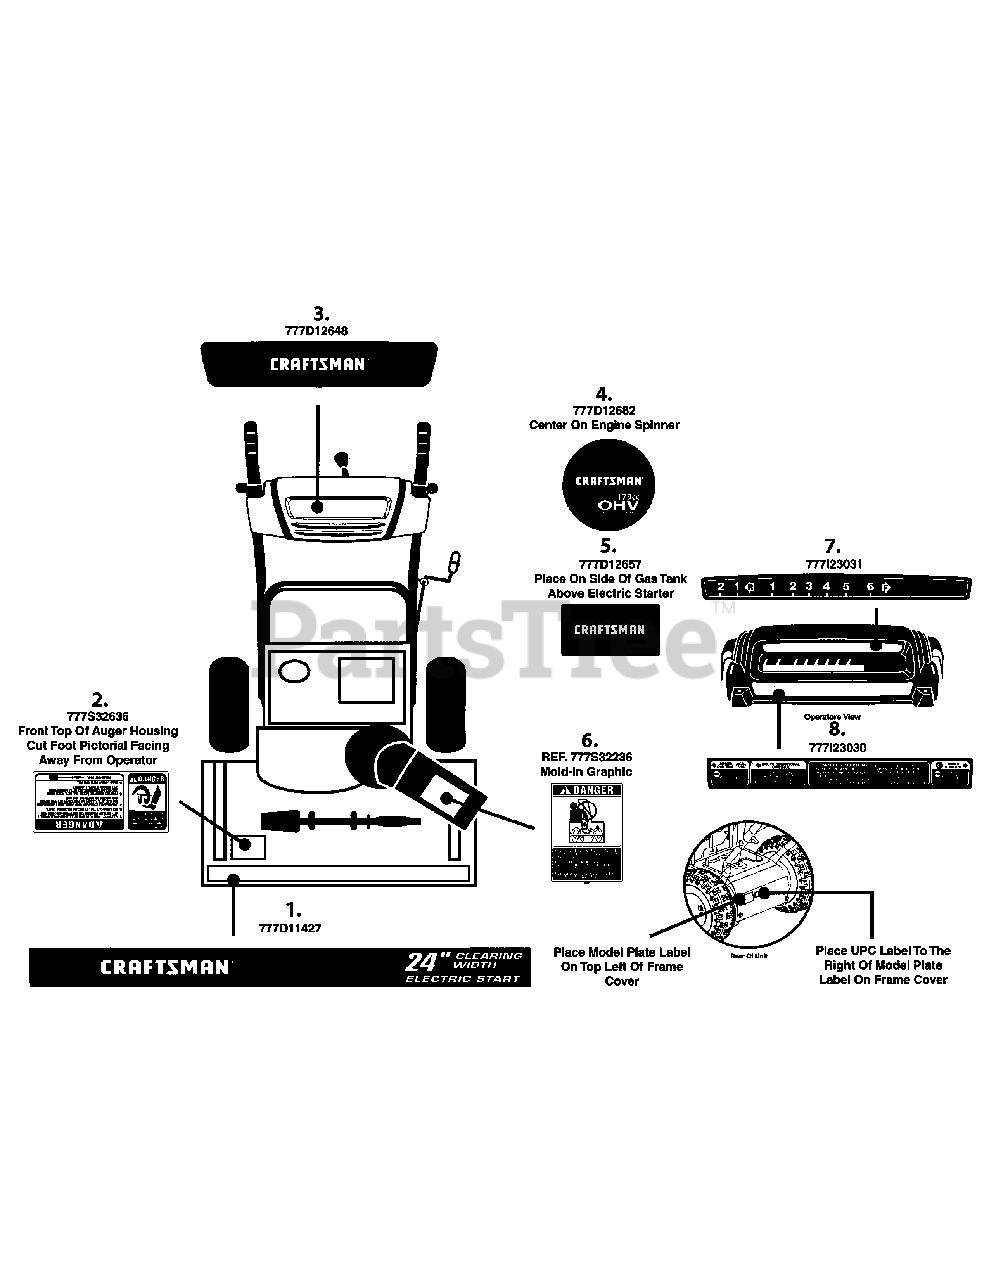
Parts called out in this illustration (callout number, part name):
1	LABEL:SNOW:HSG:CRAFTSMAN 24
2	LABEL-SNOW HOUSING
3	LABEL-SNOW PANEL COVER CRAFTSMAN
4	LABEL:SNOW:MTD ENG:CRFTSMN 179CC
5	LABEL:ENG:BTM GAS TANKCRAFTSMAN
6	LABEL:SNOW CHUTE
7	LABEL-SNOW SPEED SELECTOR
8	LABEL-SNOW PLASTIC COVER
